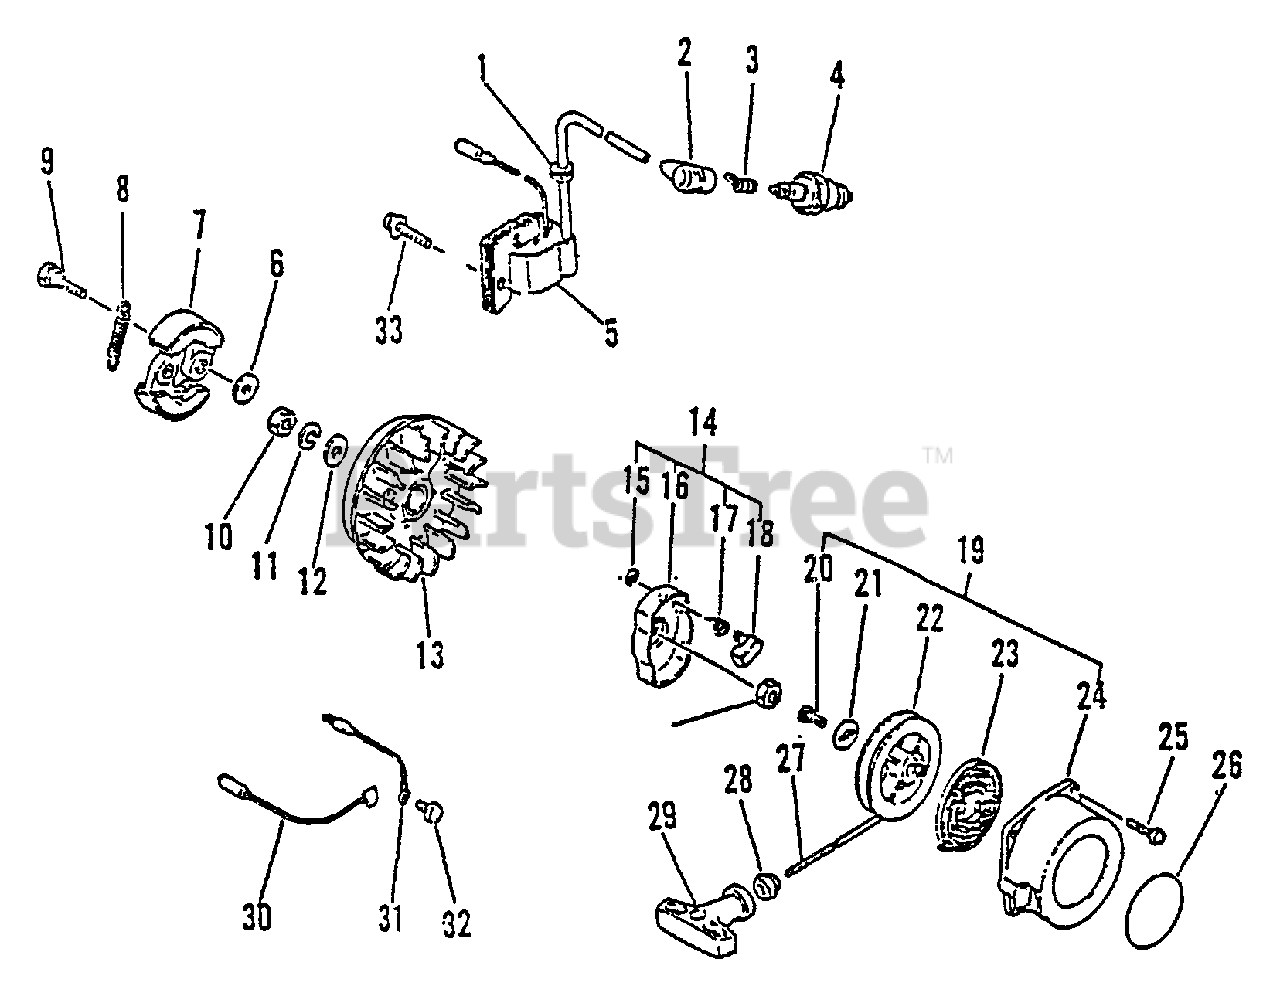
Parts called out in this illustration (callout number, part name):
2	CAP, SPARK PLUG
3	TERMINAL, SPARK PLUG CAP
4	SPARK PLUG -- BPM-7A
5	COIL, IGNITION
6	WASHER - 6
7	SHOE, CLUTCH
8	SPRING, CLUTCH
9	BOLT, CLUTCH
11	LOCKWASHER - 8
12	WASHER - 8
13	FLYWHEEL
14	STARTER PAWL ASSY
15	RING, RETAINING - 4
16	CATCHER, PAWL
17	SPRING, RETURN
18	PAWL, STARTER
19	STARTER ASSY - GRAY
21	WASHER
22	REEL, ROPE
23	SPRING, REWIND
24	CASE, STARTER
25	SCREW - 4X14
26	LABEL - ECHO
27	ROPE, STARTER - 3.5X850
28	GUIDE, ROPE
29	GRIP, STARTER
30	LEAD - GROUND
31	LEAD - GROUND
32	SCREW - 5X10
33	SCREW - 5X28
